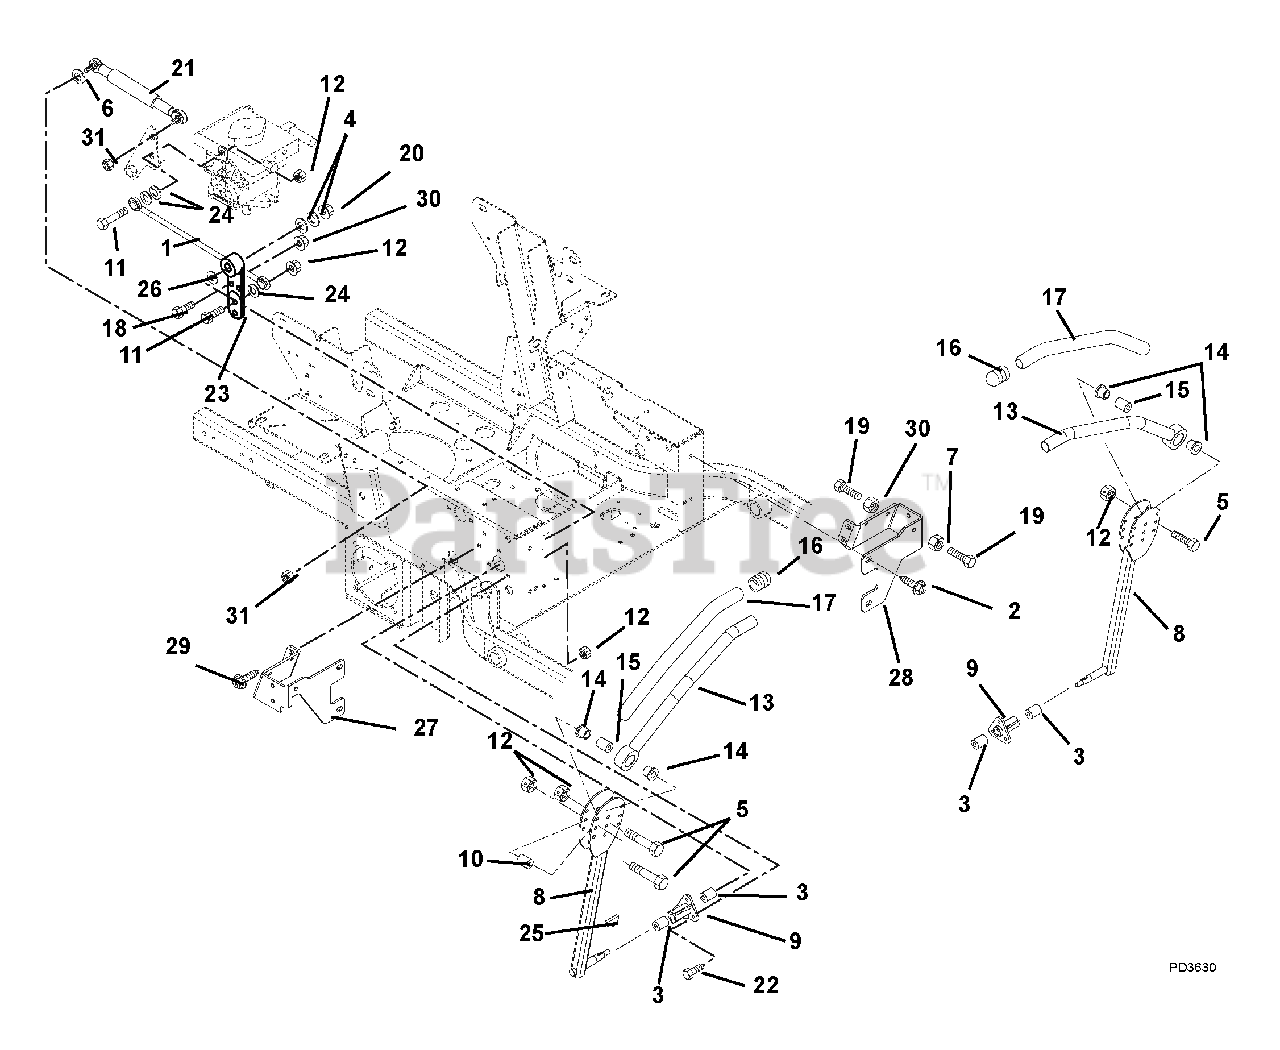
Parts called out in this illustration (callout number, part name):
1	ASSY, STEERING ROD
2	@SCR-TAP .38-16X.75 HWH TR YWZ
3	BSHG .625X.750X.500
4	@WSHR-FL-STL.406X.812X.065 YWZ
5	@BLT-HEX .31-18X1.75 GR5 YWZC
6	@WSHR-FL-STL.38X.875X.083 YWZC
7	NUT-HEX-JAM .375-16 YWZC
8	CONTROL ARM - BLACK
9	BUSHING, FLANGE
10	ECCENTRIC
11	@BLT-HEX .31-18X1.25 GR5 YWZC
12	@NUT-LK-TOP-FLG .31-18 YWZC
13	HANDLE WLDMT LH
14	BSHG-FLG .762X1.48X.44 NYL
15	SPACER .328 X .76 X 1.01
16	CAPLUG - HANDLEBAR
17	GRIP - HANDLEBAR
18	BLT-HEX .375-16X1.750 FTD YWZC
19	@BLT-HEX .38-16X1.25 GR5 YWZC
20	@NUT-LK-TOP-FLG .38-16 YWZC
21	DAMPENER, CONTROL
22	@BLT-HEX .31-18X.75 GR5 YWZC
23	ARM, PIVOT
24	@WSHR-LK .31X.078 REG YWZC
25	KEY-WDRF .13X.63 HRD#5
26	WAVE WASHER .640X.875X.125FH
27	STOP, STEERING-RH (BLACK)
28	STOP, STEERING -LH (BLACK)
29	@SCR-TAP .38-16X.50 HWH TR YWZ
30	@NUT-LK-CTR-JAM .375-16 YWZC
31	@NUT-LK-TOP-FLG .31-18 YWZC
